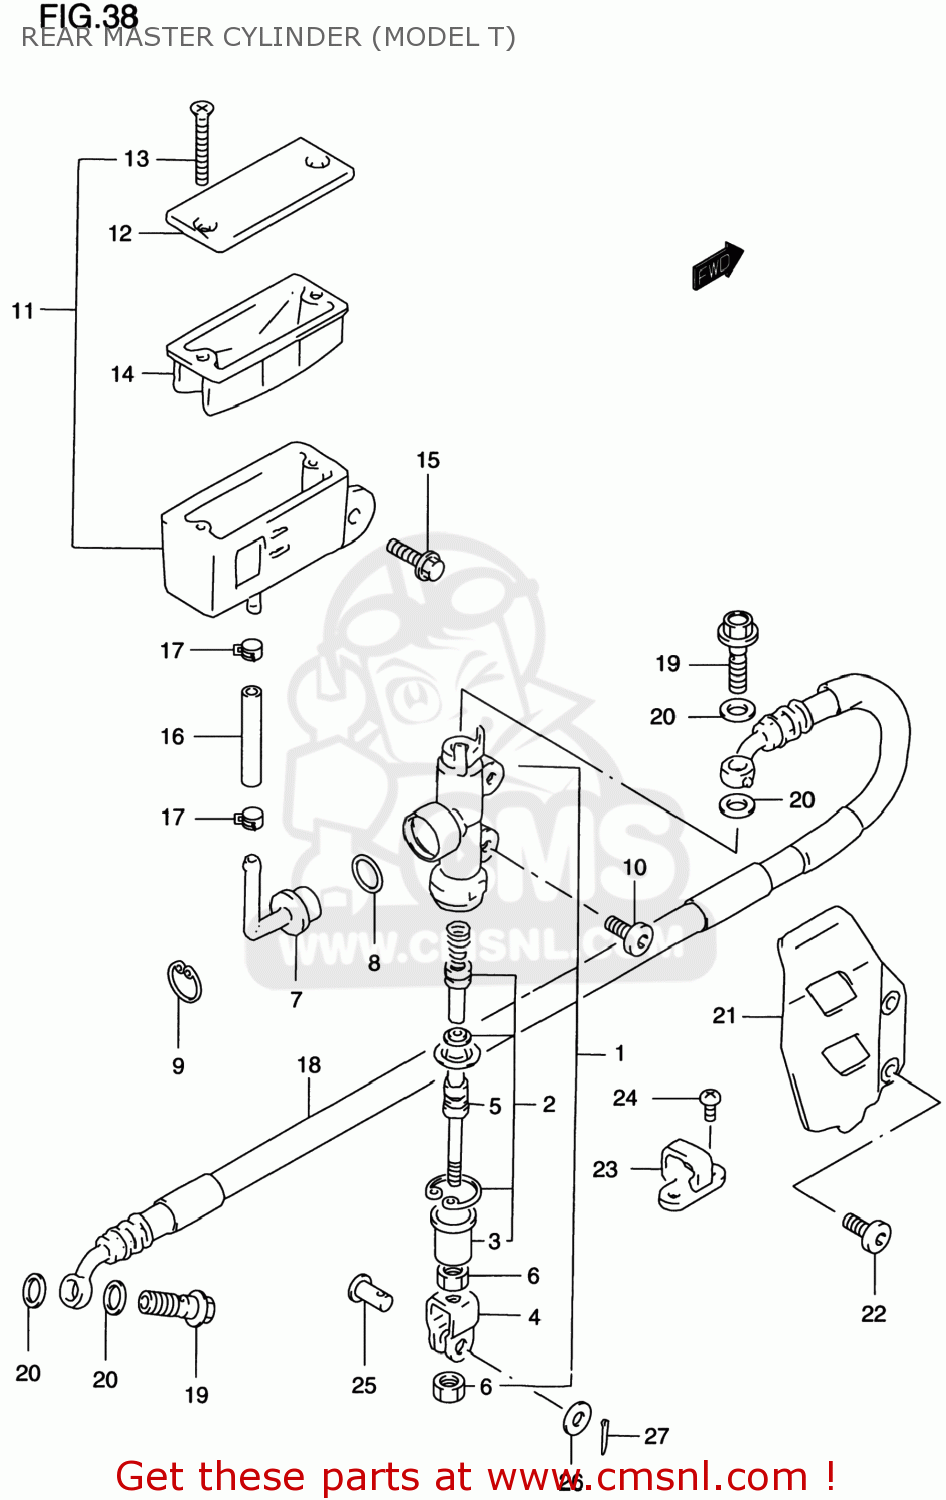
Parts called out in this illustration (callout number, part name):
1	CYLINDER ASSY,RR MASTER
2	PISTON/CUP SET
3	BOOT
4	YOKE
5	ROD,PUSH
6	NUT
7	CONNECTOR
8	O RING
9	CIRCLIP
10	SCREW(6X16)
11	TANK ASSY,RESERVOIR
12	CAP
13	SCREW
14	DIAPHRAGM
15	BOLT
16	HOSE,RESERVOIR TANK
17	CLAMP,RESERVOIR HOSE
18	HOSE COMP,REAR BRAKE
19	BOLT UNION
20	WASHER(10X15X1.5)
21	GUARD,RR MASTER CYLINDER
22	SCREW(6X16)
23	GUIDE,RR BRAKE HOSE
24	SCREW
25	PIN(8X20)
26	WASHER(8.5X13X1.6)
27	PIN
